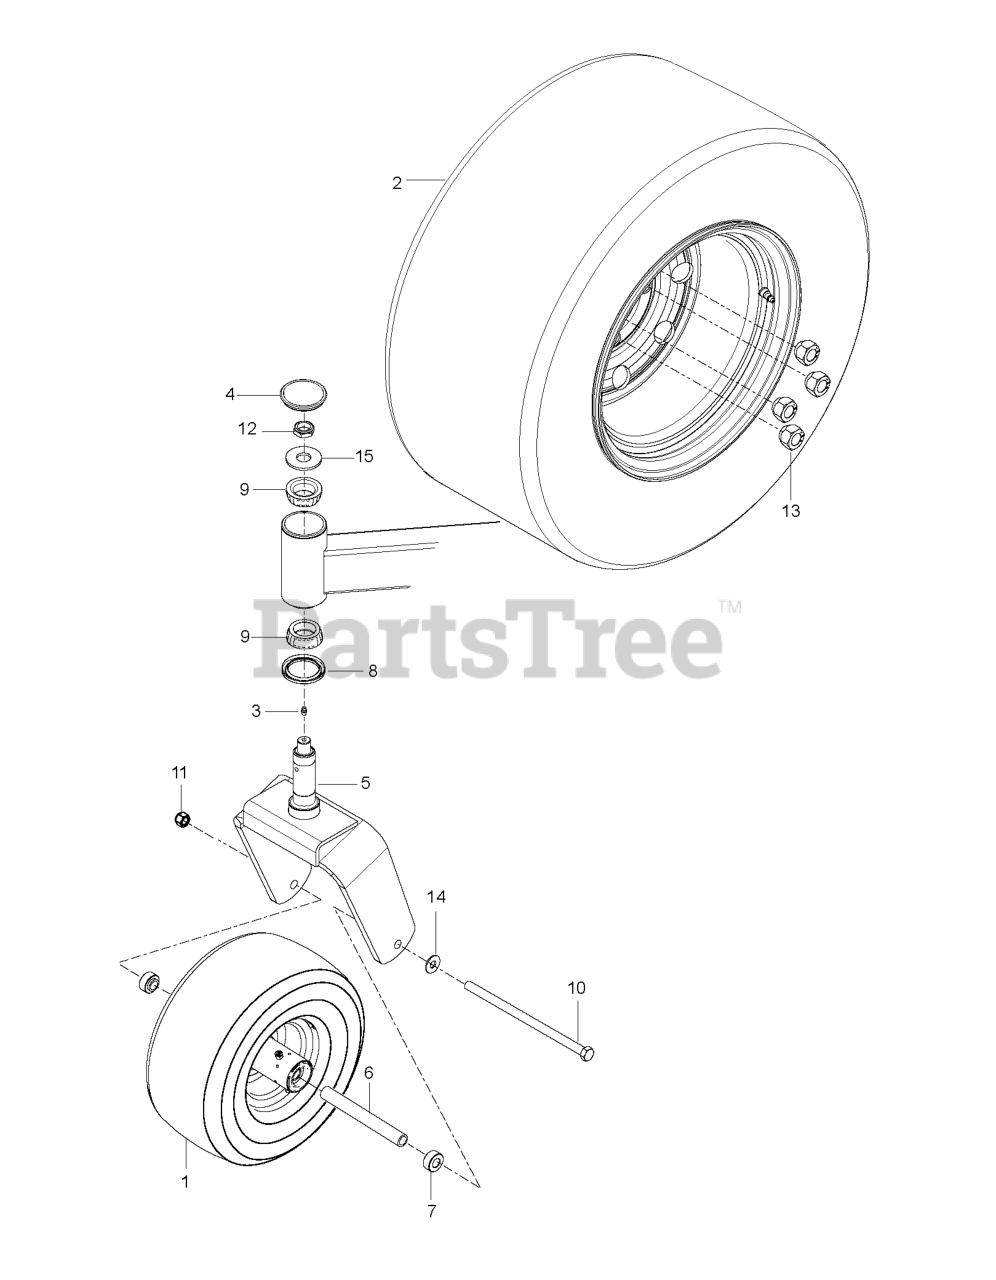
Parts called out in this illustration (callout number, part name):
1	TIRE 13X6.5-6 NO FLAT GLOSS BL
2	TIRE 24X12-12 NHS TURFSMART GL
4	CAP, DUST
5	FORK CASTER SNAPPER RED X672
6	SPACER.HUB
7	SPACER.AXLE
8	SEAL, BEARING
9	CONE, LM67048
10	HEX SCREW 1/2-13 X 9.5 GR5
11	NUT, 1/2-13 HEX FLG NYLOC ZD
12	NUT, 3/4-16 HEX THIN NYLOC ZD
13	NUT.1/2-20.UNF-2B.GR.8.YL
14	WASHER 1/2" FLAT
15	WASHER, 3/4 HARDENED
